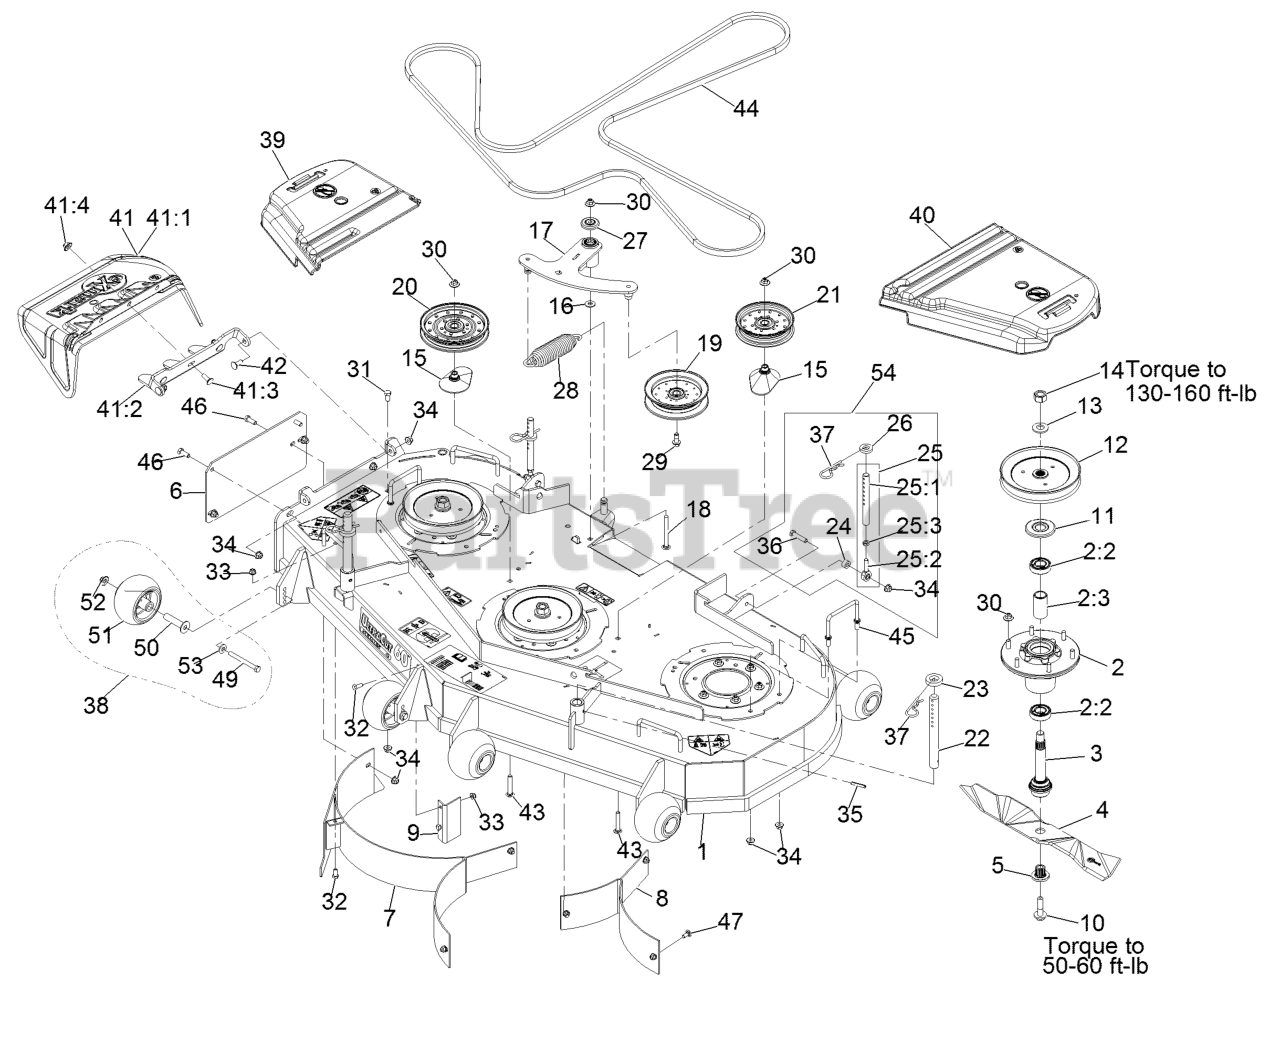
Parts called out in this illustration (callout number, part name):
1	ASM, DECK W/ DECALS, 60"
2	ASM-CUTTER HSG WITH BEARINGS
2:2	BEARING-BALL
2:3	SPACER-BEARING
3	ASM-SPINDLE AND SEAL
4	Blade-Extreme 2, 20.50"
5	BUSHING,SPLINED
6	PLATE-MULCH COVER, 604
7	BAFFLE WLD RH MULCH
8	XREF 1-632948-03 (EXMARK)
9	BAFFLE,BLOCKER MK604
10	SCREW,SEMS 1/2-20 X 2.19
11	GUARD,BEARING TOP .989
12	SHEAVE,BLADE DRIVE 7.25
14	NUT-HEX
15	SPACER-PULLEY
16	WASHER-FLAT
17	ASM, DECK IDLER
18	SCREW-CARR
22	ROD,DECK SUPPORT
23	SPACER-DECK SUPPORT
25:1	LINK,SUPPORT
25:2	BALLJOINT
25:3	NUT-HJ
27	GUARD-TOP
28	SPRING-EXTENSION
29	SCREW-HFH
30	Nut-Nyloc 3/8-16 Flg
31	SCREW-HH
32	SCREW-HH
33	NUT-HF, NI
34	NUT-HF, NI
36	SCREW-HH
37	PIN,HAIR COTTER
38	KIT, ANTI-SCALP ROLLER
39	COVER-BELT, RH
40	COVER-BELT, LH
41	ASM,DISCHARGE CHUTE
41:1	CHUTE,DISCHARGE
41:2	BRACKET,DISCHARGE CHUTE
41:3	SCREW-CARR
41:4	Nut-Nyloc 3/8-16 Flg
42	SCREW-CARR
43	BOLT-CARR, SHORT NECK
44	BELT, DECK DRIVE
45	WIREFORM-COVER
46	SCREW-HH
47	BOLT-CARR
49	SCREW-HH 3/8-16 X 3 3/4 GR 8
50	AXLE, ROLLER
51	ROLLER-SCALP, ANTI
52	Nut-Nyloc 3/8-16 Flg
53	WASHER-BELLEVILLE
54	KIT,SUPPORT LINK W/PIN
